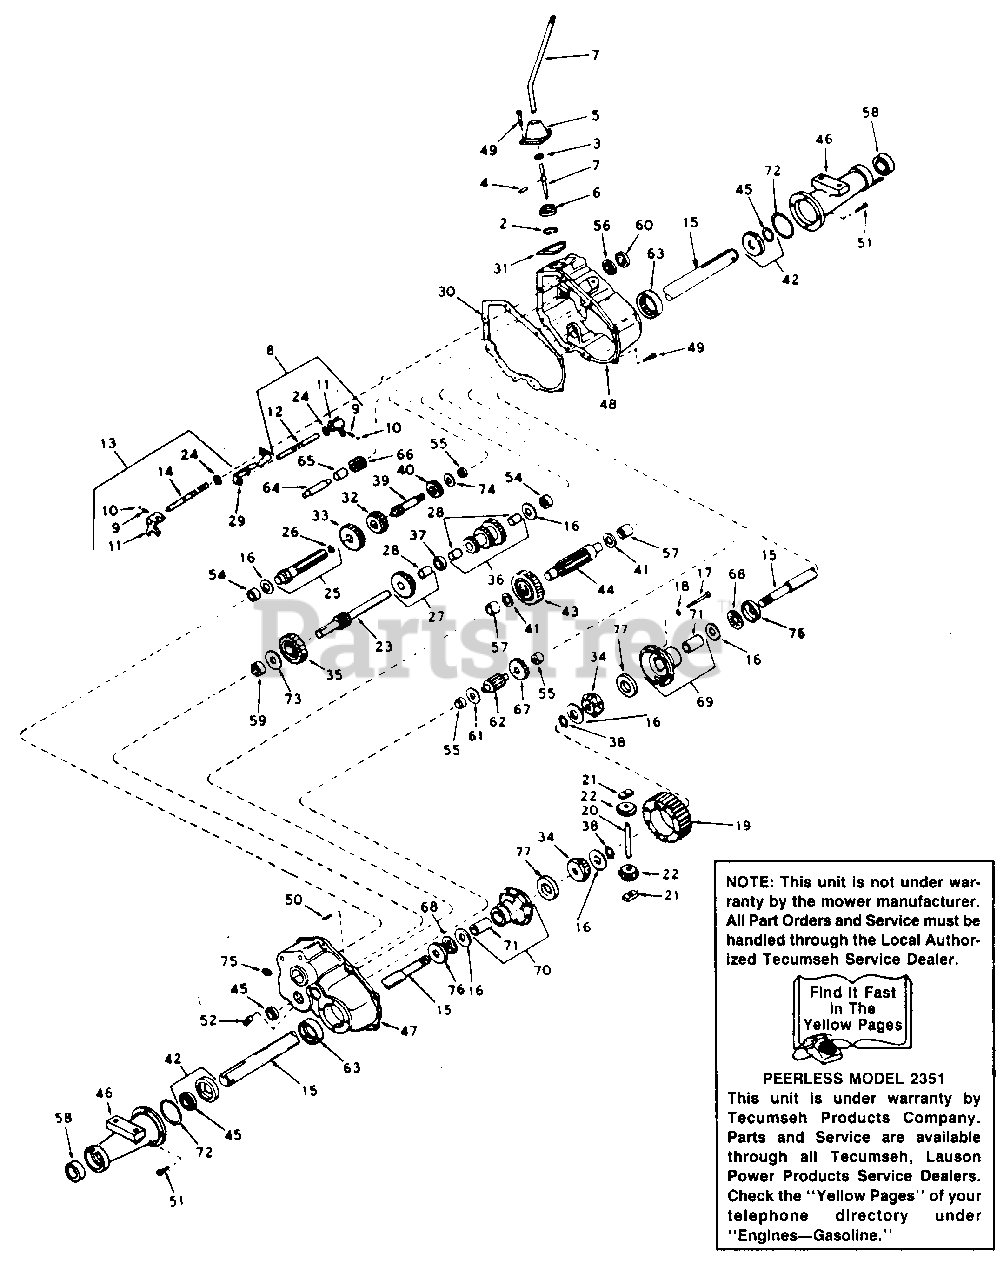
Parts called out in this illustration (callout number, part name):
2	Ring, Snap
3	Ring, Quad
4	Pin, Roll
5	Housing, Shift Lever
6	Keeper, Shift Lever
7	Lever, Shift
8	Rod Ass'y., Shift
9	Spring
10	Ball, Steel
11	Fork, Shifter
12	Rod, Shifter
13	Rod Ass'y., Shift
14	Rod, Shifter
15	Axle (18-11/32" Long)
16	Washer, Thrust
17	Scr., Hex Hd., 1/4-20 x 21/2
18	Lock Washer, 1/4"
19	Gear, Ring
20	Pin, Drive
21	Block, Drive
22	Pinion, Bevel
23	Shaft and Gear, Brake
24	Ring, Snap
25	Shaft and Bearing Ass'y., Pinion
26	Bearing, Needle
27	Gear Cluster Ass'y.
28	Bushing
29	Stop, Shifter
30	Gasket, Case and Cover
31	Gasket, Shifter Lever Housing
32	Gear, Shifting
33	Gear, Shifting
34	Gear, Bevel
35	Gear, Idler
36	Gear Cluster Ass'y.
37	Spacer
38	Ring, Snap
39	Shaft, Input
40	Spur Gear, Input Shaft
41	Washer, Thrust
42	Seal and Retainer Ass'y., Oil
43	Gear, Output
44	Pinion, Output
45	Seal, Oil
46	Housing, Axle
47	Cover Ass'y., Transaxle
48	Case Ass'y., Transaxle
49	Screw, Socket Hd., 1/4-20 x 3/4
50	Pin, Dowel
51	Screw, Hex Hd. Sems, 5/16-18 x 1
52	Plug, Magnetic Drain
54	Bearing, Needle
55	Bearing, Needle
56	Bearing, Ball
57	Bearing, Needle
58	Bearing, Ball
59	Bearing, Needle
60	Seal, Oil
61	Washer
62	Shaft and Pinion
63	Bearing, Needle
64	Shaft, Reverse Idler
65	Spacer, Reverse Idler
66	Idler, Reverse
67	Spur Gear (22 Teeth)
68	Bearing, Thrust
69	Carrier Ass'y., Differential
70	Carrier Ass'y, Differential
71	Bushing
72	"O" Ring
73	Washer, Thrust
74	Washer, Thrust
75	Plug, Pipe
76	Race, Thrust
77	Washer
